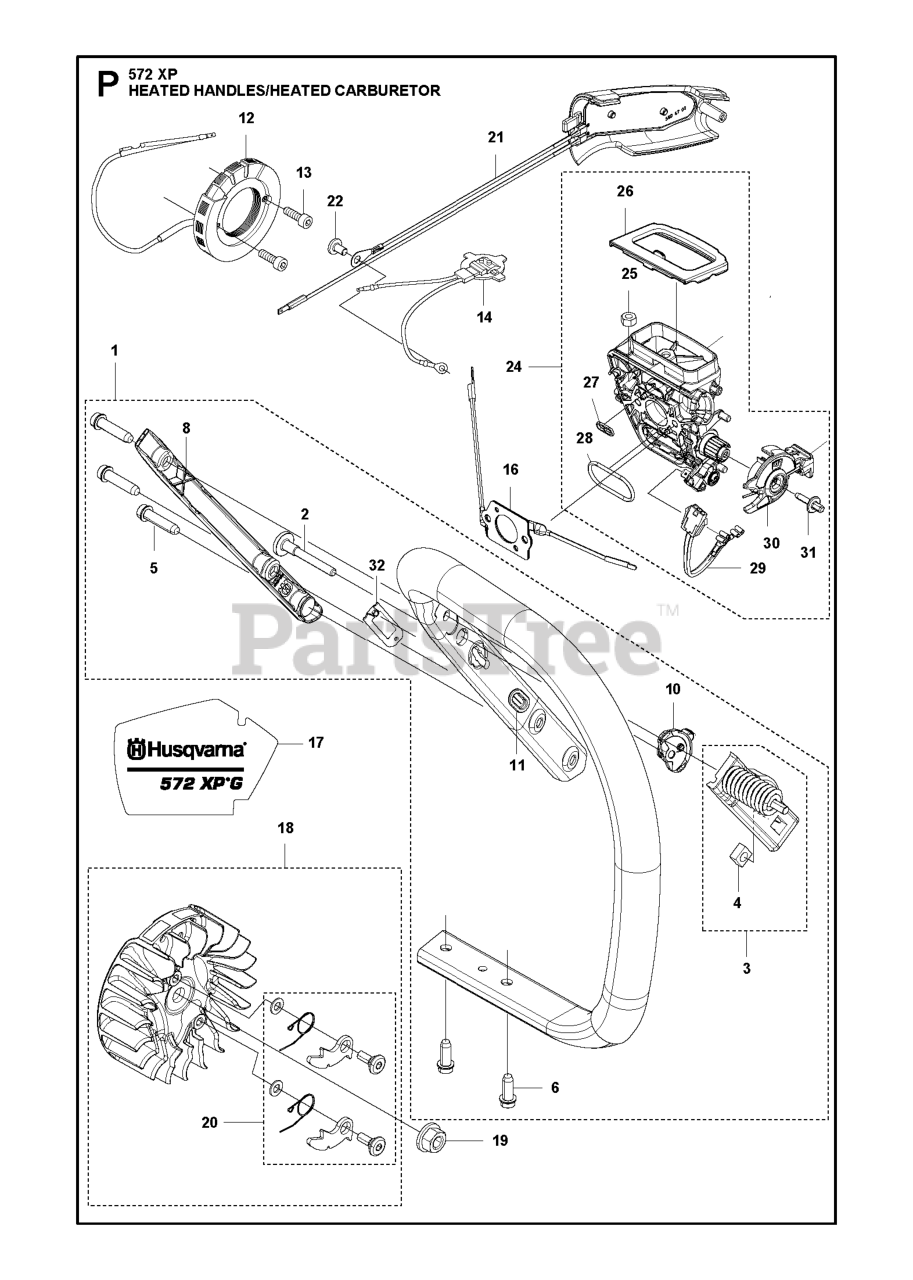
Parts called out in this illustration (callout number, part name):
1	FRONT HANDLE ASSY KIT HEATED -
2	SCREW ITXPANM MOVEMENT LIMITER
3	ANTIVIBRATION ELEMENT ASSY HEA
3	ANTIVIBRATION ELEMENT ASSY HAR
8	COVER FRONT HANDLE HEAT
12	GENERATOR STATOR ASSY
13	SCREW ITXSCM M4X15 T27 12.9 T
14	THERMOSTAT ASSY
16	FOIL ELEMENT ASSY
17	DECAL STARTER 572XPG
18	FLYWHEEL ASSY SPARE PART H572X
19	NUT W/ WASHER
20	PAWL KIT - SPARE PART H565/H57
21	HANDLE INSERT ASSY HEAT
24	INLET ELBOW HEATED SPARE PART
26	SEALING FILTER HOLDER
29	WIRING ASSY STOP
30	CHOKE CONTROL ASSY CHOKE/STOP
32	PROTECTION FRONT HANDLE, HEAT
